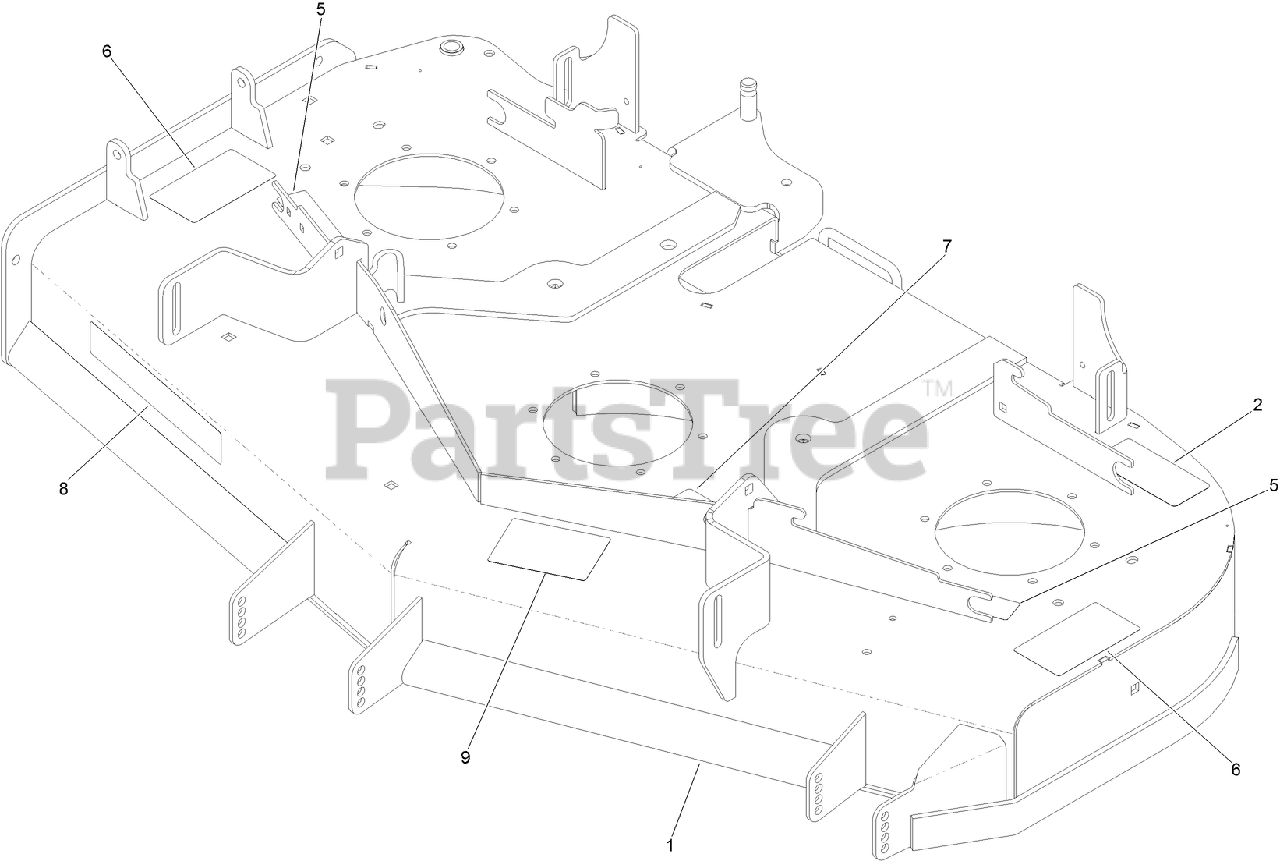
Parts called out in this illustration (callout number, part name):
1	DECK DECAL ASSEMBLY
2	DECAL-TORQUE, BLADE BOLT
5	DECAL-COVER, MISSING
6	DECAL-DANGER
7	DECAL-ROUTING, BELT
9	DECAL-SCALP, ANTI
